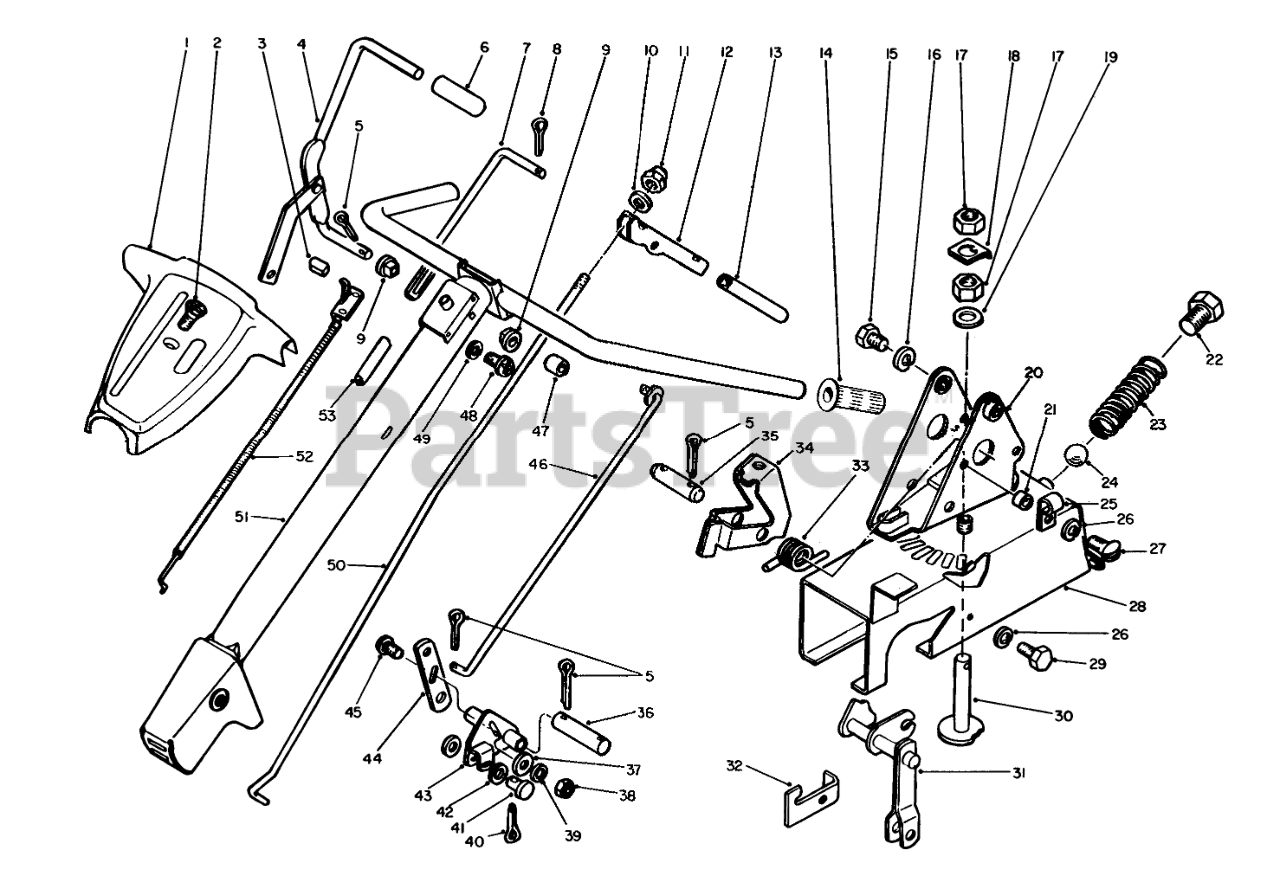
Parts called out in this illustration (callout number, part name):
1	Handle Shroud w/Decal
2	Machine Screw
3	Grip-Throttle Control
4	Control Handle
5	PIN-COTTER
6	Grip
7	Link
8	PIN-COTTER
9	Bushing
10	WASHER-FLAT
11	NUT-LOCK, CONE
12	Lever
14	Grip
15	SCREW-HH
16	WASHER-LOCK
17	NUT-JAM
18	Lock
19	WASHER-THRUST
20	Pivot
21	Spacer-Clamp
22	Hex Hd. Capscrew
23	Spring-Detent
24	Ball-Detent
25	Clamp
26	WASHER-LOCK
27	1/4-20 X 5/8 RD HD SC
28	Tunnel
29	SCREW-HH
30	Plunger
31	Cam Assembly
32	Retainer
33	Spring
34	Pawl
35	Pin
36	Pin
37	Spacer
38	NUT-LOCK, CONE
39	WASHER-LOCK
40	PIN-COTTER
41	Clevis Pin
42	WASHER-FLAT
43	Bellcrank
44	Lever
45	BOLT-CARR
46	Control Rod
47	Spacer
48	Pan Hd. Machine Screw
49	WASHER-LOCK, EXT
50	Control Rod
51	Handle
52	Throttle Control
53	Slide
